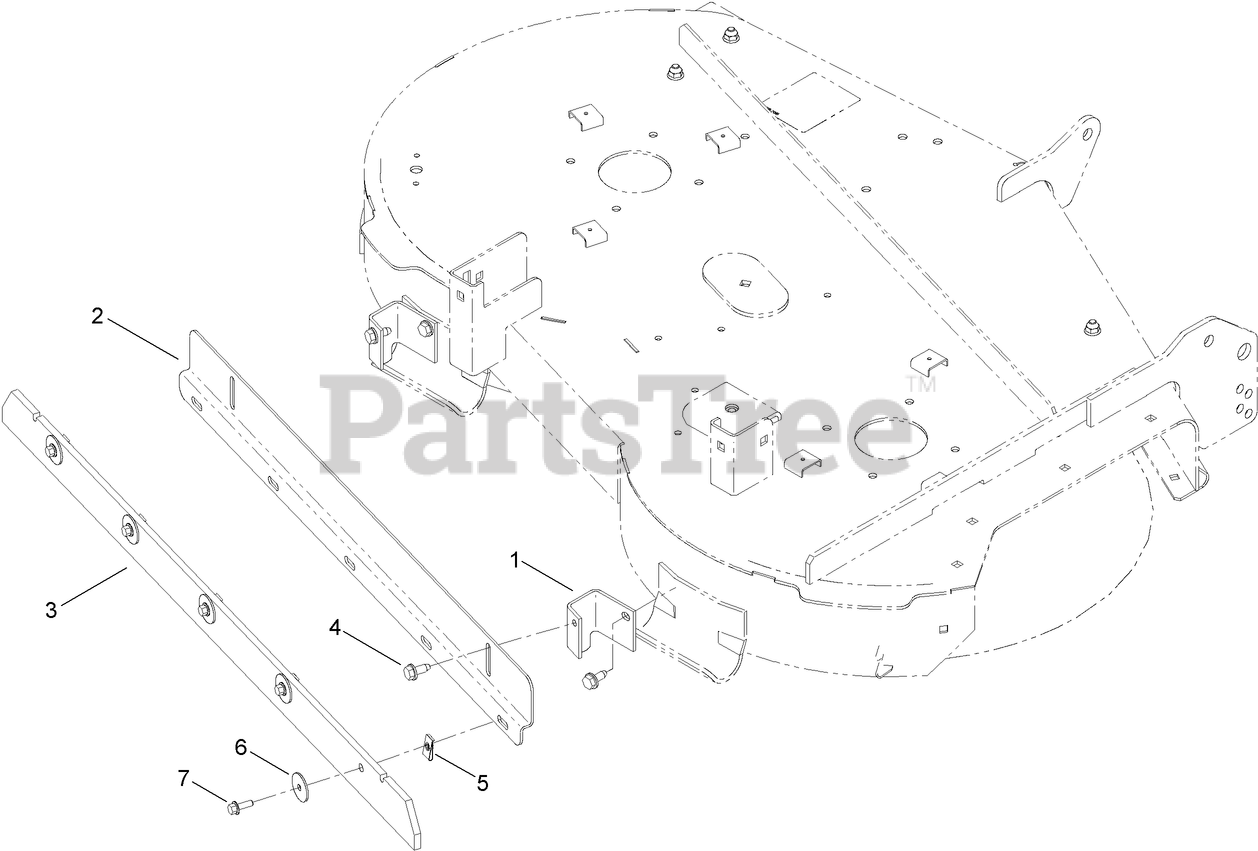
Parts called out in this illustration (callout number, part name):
2	BRACKET-STRIPING
4	SCREW-HWHTF
5	NUT-SPEED
6	WASHER-FLAT
7	SCREW-HHF
